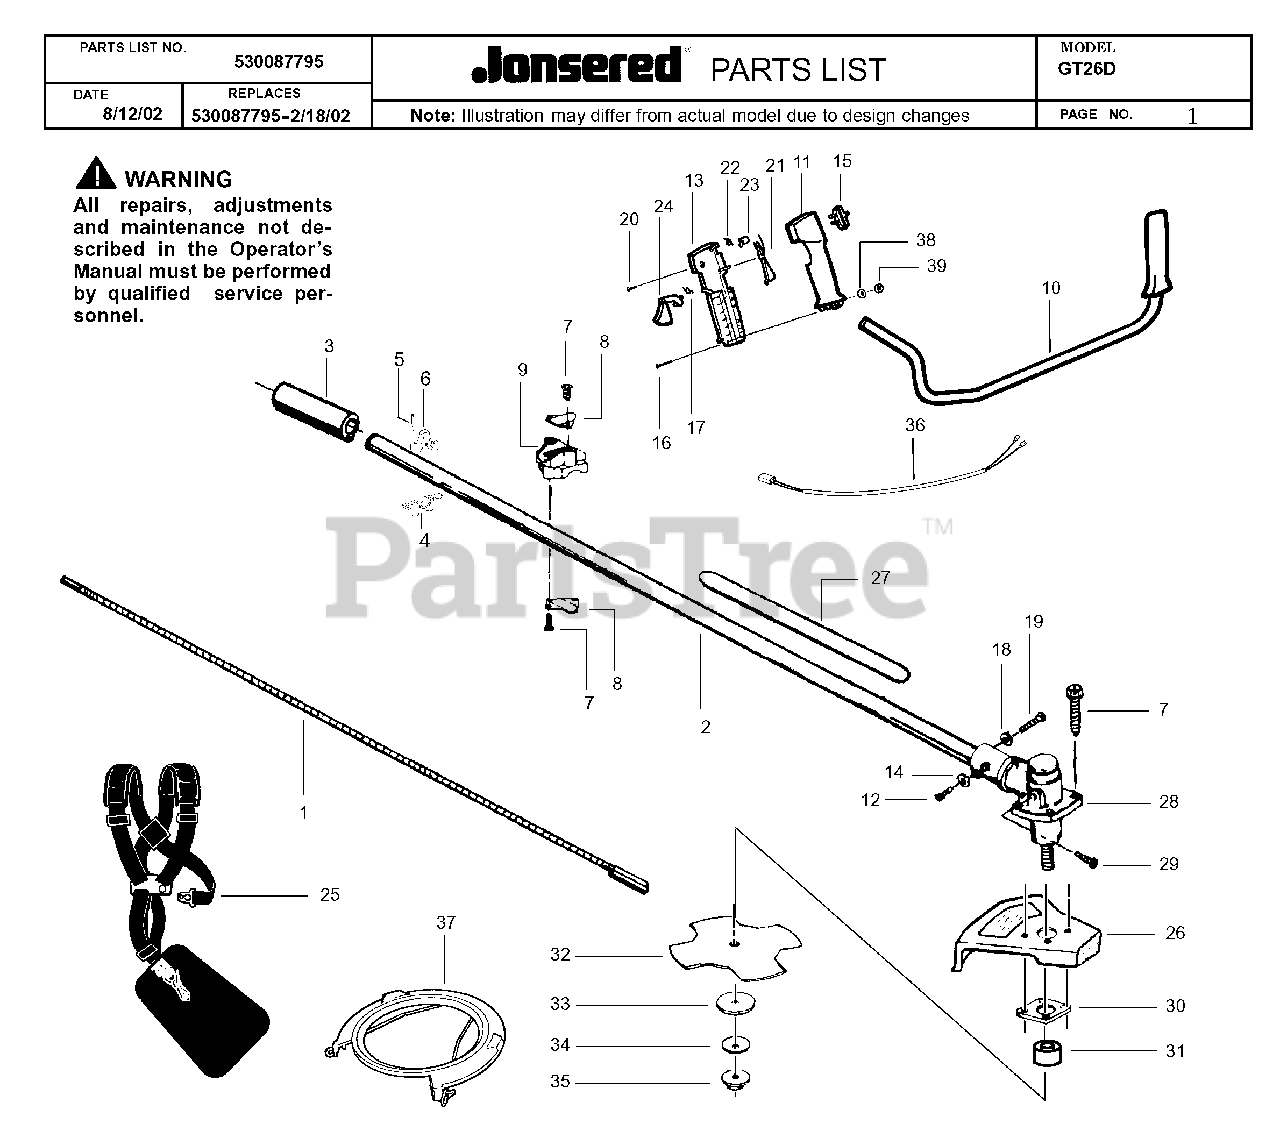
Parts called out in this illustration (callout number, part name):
1	SHAFT-FLEX (57").
2	DRIVE SHAFT TUBE
5	CLAMP HARNESS - UPPER
6	SCREW-10-16 X 1-3/8 PLA
8	BRACKET-HANDLEBAR
9	CLAMP-HANDLEBAR
10	HANDLEBAR
12	SCREW-10-24 X 7/16 (HEX
14	LOCKWASHER-LOCATOR-TYPE 2
15	START/STOP SWITCH
16	SCREW 10-24X1-5/8
17	SPRING
18	LOCKWASHER
19	SCREW-1/4-20X1 HEX SOC
21	THROTTLE LOCKOUT
23	THROTTLE LOCK
24	THROTTLE TRIGGER
25	STRAP SHOULDER
28	GEAR BOX ASSY/TYPE 1
29	SCREW-5/16-24X3/8 HEX S
30	PLATE-SHIELD RETENTION
32	BLADE
33	WASHER-FLAT.
35	NUT-FLANGE (LH)
37	BRUSH BLADE PROTECTOR
530029064	DECAL-BLADE DIRECTION
530031098	HEX KEY 3/16"
530031159	HEX WRENCH 5/32
